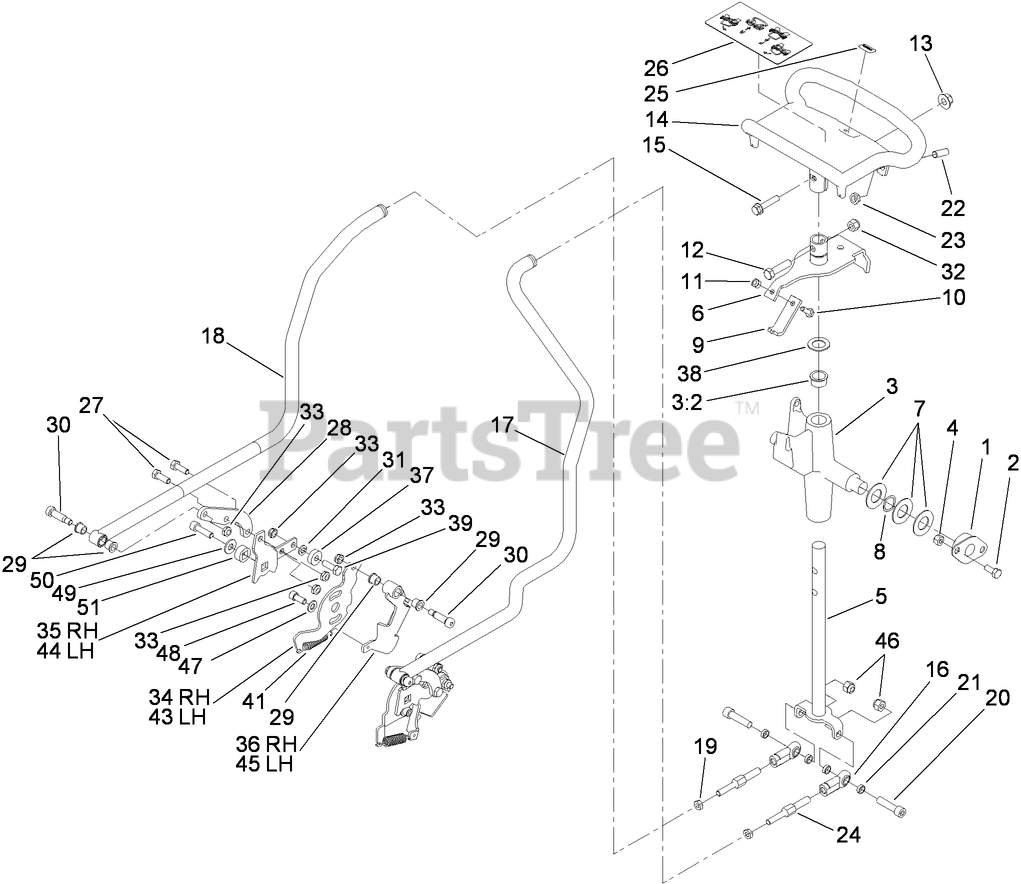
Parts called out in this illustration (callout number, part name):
1	BUSHING
2	SCREW-HH
3	CONTROL SUPPORT ASM
3:2	BEARING-FLANGE
4	NUT-LOCK, NI
5	ROD-DRIVE
6	LEVER-PIVOT
7	WASHER-FLAT
8	WASHER-SPRING, WAVE
9	PLATE-NEUTRAL
10	SCREW-HH
11	NUT-LOCK, NI
12	SCREW-HH
13	NUT-FLANGE
14	HANDLE-CONTROL
15	SCREW-HHF
16	JOINT-BALL END, LH
17	ROD-CONTROL, LH
18	ROD-CONTROL, RH
19	NUT-JAM
20	SCREW-HSH
21	SPACER-PLATE, RETAINING
22	SCREW-SET
23	NUT-JAM
24	LINK-CONTROL, ADJUSTMENT
25	DECAL
26	DECAL-TRACTION
27	SCREW-HH
28	PLATE-ADAPTER, CONTROL, RH
29	BUSHING-FLANGE
30	BOLT-SHOULDER
31	WASHER-LOCK
32	NUT-LOCK, NI
33	NUT-LOCK, NI
34	PLATE-BASE, RH
35	PLATE-ARM, RETURN
36	PIVOT-RH
37	BEARING-BALL
38	WASHER-THRUST
39	SCREW-HH
41	SPRING-EXTENSION
43	PLATE-BASE, LH
44	PLATE-ARM, RETURN, LH
45	PIVOT-LH
46	NUT-LOCK, NI
47	WASHER-PLAIN
48	SCREW-HSH
49	WASHER-FLAT
50	SCREW-HSH
51	LOCK-TRUNION
